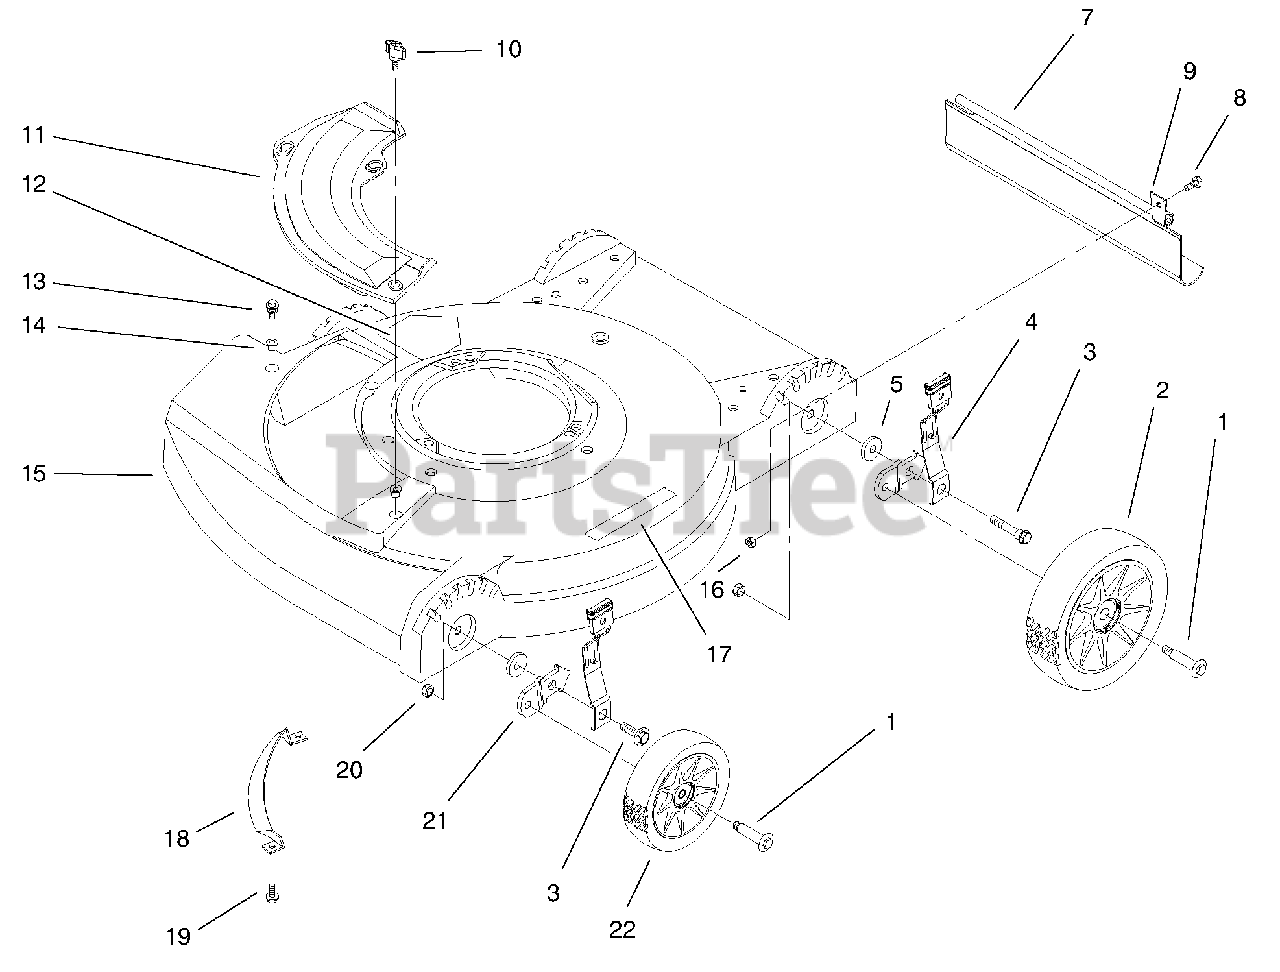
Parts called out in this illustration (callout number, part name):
2	8" Whel/Tire ASM
4	Knob&spring Formc
7	Shield-Trailing
8	Screw-HH
9	Clamp-Shield
11	Plate-Chute Opening
12	Decal-Cut Finger
13	Screw-Sems
14	Grommet-Plastic
15	Hsg-Commercial 21"
16	Nut-Lock Ni
17	Decal-Safety Instruct
18	Toe Bar 21"
19	Screw/Washer
20	Nut-Lock Ni
21	Whl Hgt Brkt
22	6" Whel/Tire ASM
